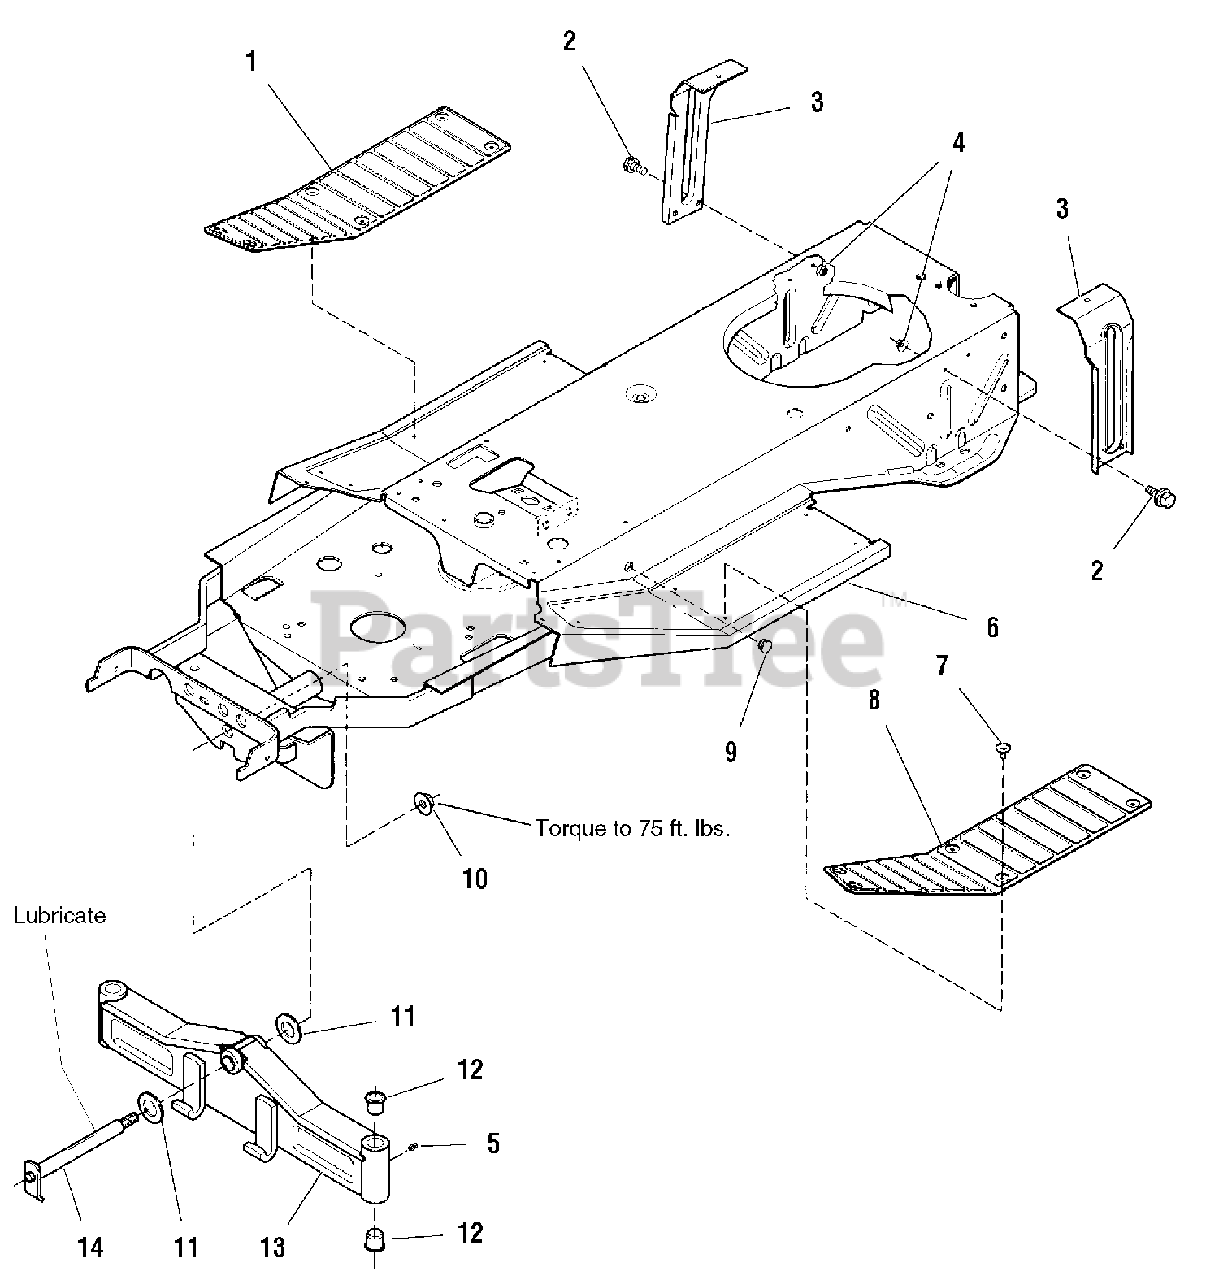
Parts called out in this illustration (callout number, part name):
1	PAD, Footrest, RH
2	CAPSCREW, Hex Flange Head, Whizlock, 3/8-16 x 1
3	SUPPORT, Seat
4	NUT, Hex Nylon Lock, 3/8-16
5	GREASE FITTING
6	FRAME ASSEMBLY
7	FASTENER, Panel
8	PAD, Footrest, LH
10	NUT, Hex Full, Lock, 3/4-16
11	WASHER, Special
13	AXLE ASSEMBLY, Front
14	AXLE PIVOT ASSEMBLY
